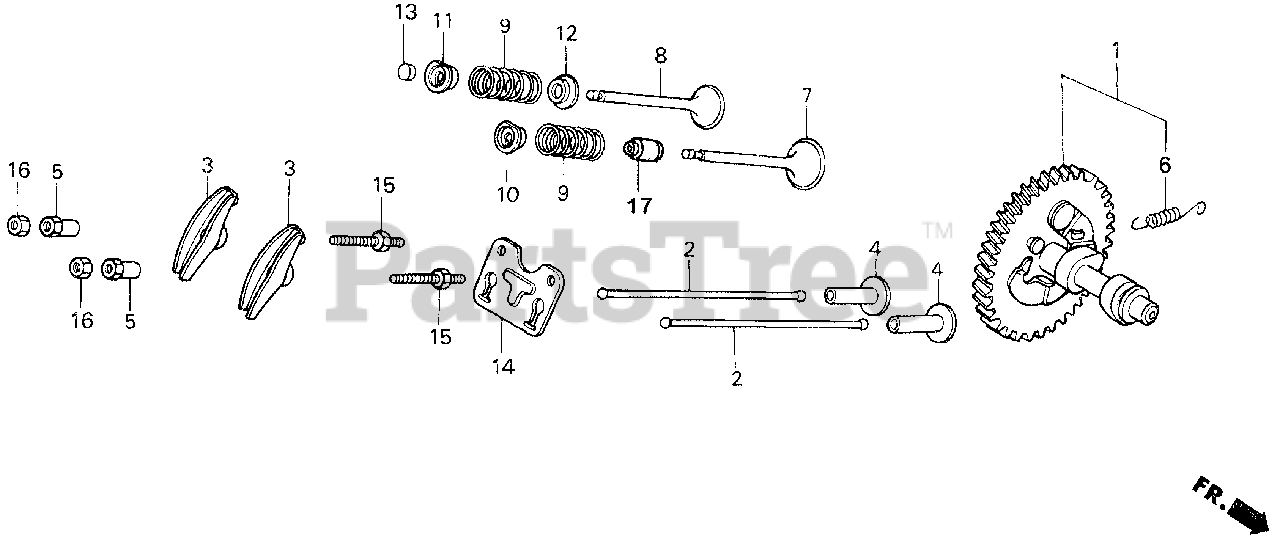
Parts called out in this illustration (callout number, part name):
1	CAMSHAFT ASSY.
1	CAMSHAFT
2	ROD, PUSH
3	ARM, VALVE ROCKER
4	LIFTER, VALVE
5	PIVOT, ROCKER ARM
6	SPRING, WEIGHT RETURN
7	VALVE, IN.
8	VALVE, EX.
9	SPRING, VALVE
10	RETAINER, IN. VALVE SPRING
11	RETAINER, EX. VALVE SPRING
12	SEAT, VALVE SPRING
13	ROTATOR, VALVE
14	PLATE, PUSH ROD GUIDE
15	BOLT, PIVOT (8MM)
16	NUT, PIVOT ADJ.
17	SEAL, VALVE STEM
